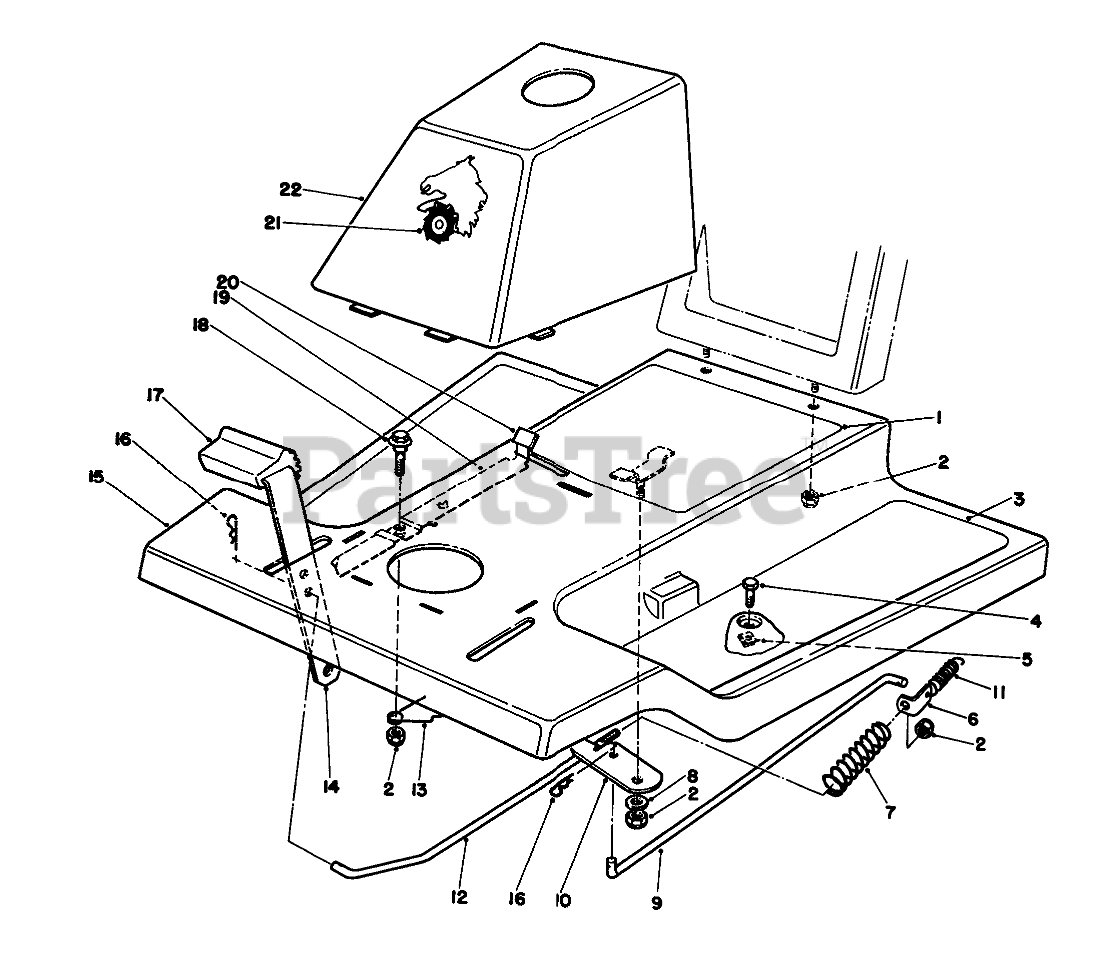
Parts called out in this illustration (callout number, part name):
1	DECAL - INSTRUCTION
2	NUT-LOCK, NI
3	TREAD-FOOT
4	SCREW-HH
5	NUT-TINNERMAN
6	BRACKET-BRAKE RETURN
7	SPRING-TRACTION BRAKE
8	WASHER-PIVOT
9	ROD-TRANS BRAKE
10	Lever-Brake, Bellcrank
11	SPRING-IDLER
12	ROD-FRONT BRAKE
13	SPRING-PARKING BRAKE
14	Pedal-Brake & Clutch
15	Body W.A.-Front
16	PIN-COTTER
17	PAD-PEDAL
18	SCREW-SHOULDER
19	Parking Brake
20	TIP-PARKING BRAKE
21	DECAL - HORSEHEAD
22	Tower (Incl. Ref. #21)
